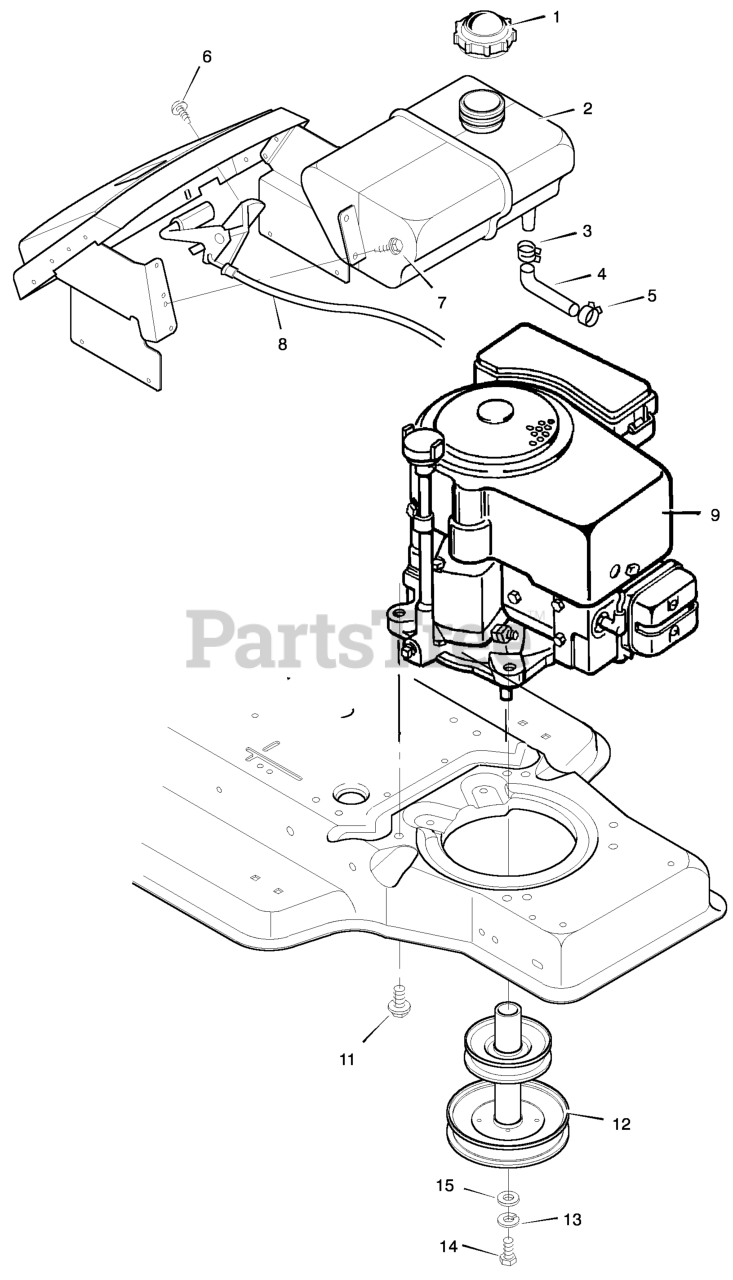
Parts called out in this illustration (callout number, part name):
1	Fuel Cap
2	Fuel Tank
3	Hose Clamp
4	Fuel Line
5	Hose Clamp
8	Throttle Control
9	Engine *
11	Bolt, Engine Mount
12	Stack Pulley Assembly
13	Lockwasher
14	Bolt, Hex
